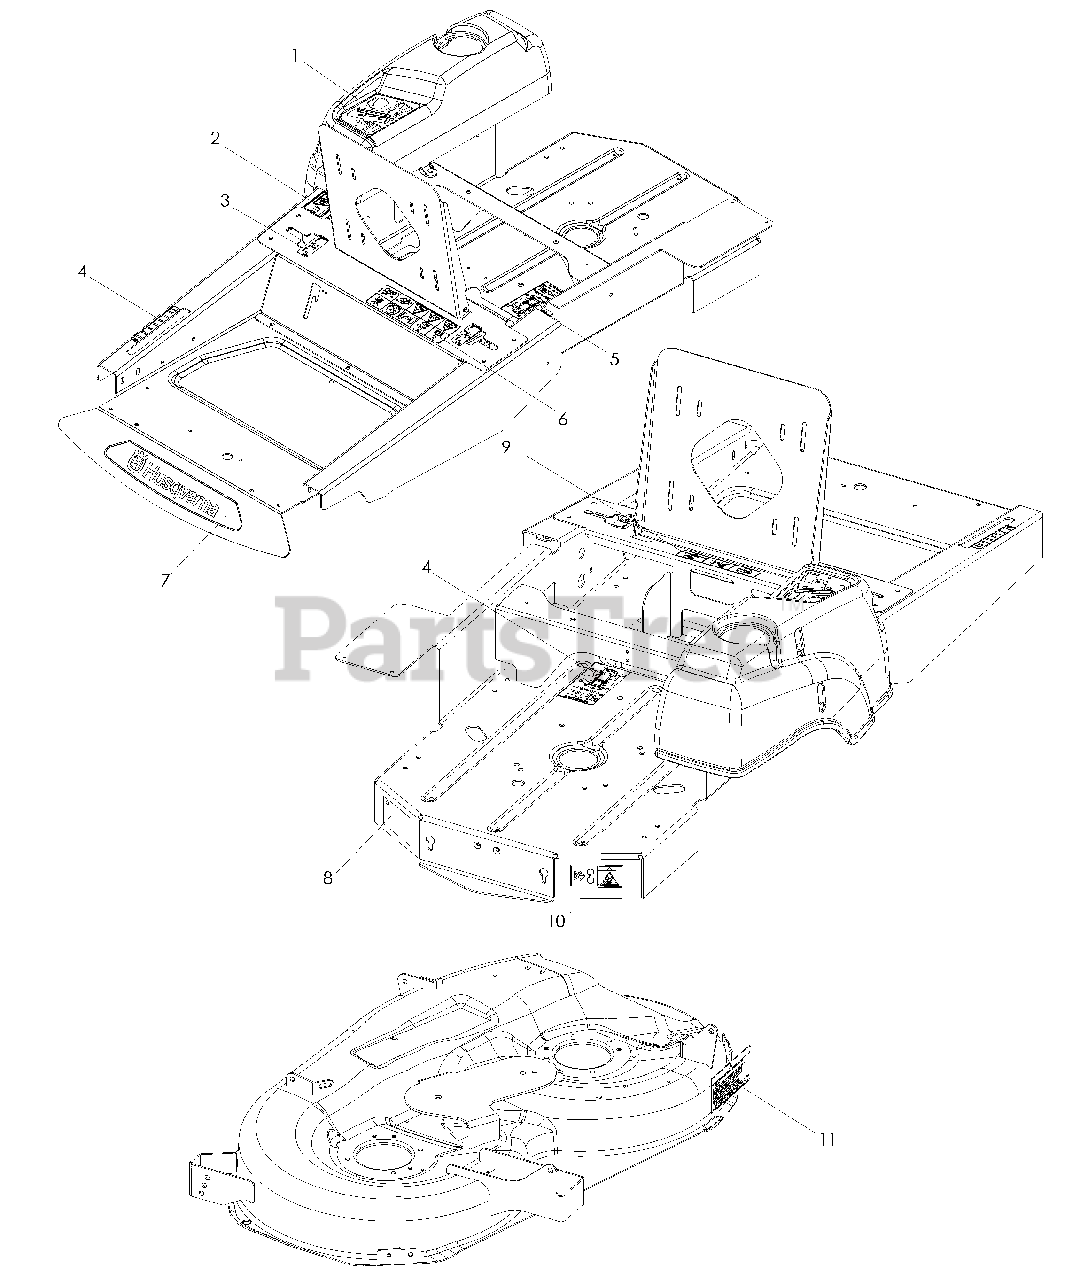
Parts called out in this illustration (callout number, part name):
1	DECAL, IGNITION CONSOLE
2	DECAL, EXIT MOWER
3	DECAL, HEIGHT, CE
4	DECAL, MOTION CONTROL
5	DECAL, SERVICE
6	DECAL, WARNING
7	DECAL, HUSQVARNA
8	DECAL, DO NOT TOW
9	DECAL, BATTERY WARNING
10	DECAL, DANGER BELT
11	DECAL, DISCHARGE
